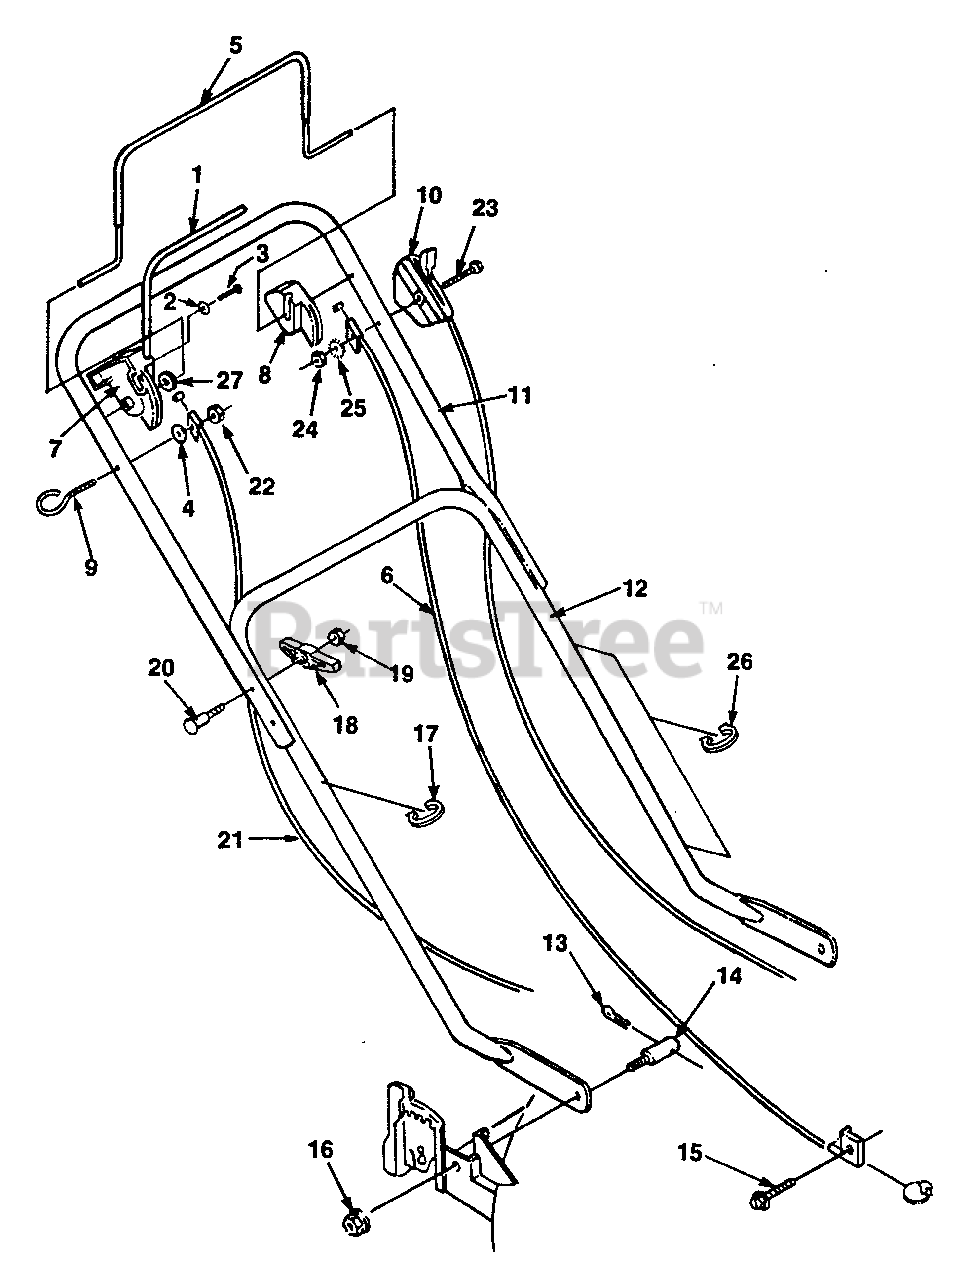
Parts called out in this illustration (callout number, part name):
1	TRACTION LEVER
2	WASHER - 1/4"
3	SCREW - 10-16×1/2" -- HEX CAP
4	WASHER - CARVED
5	BAIL - BRAKE CONTROL
6	CONTROL, MANUAL START
7	ACTUATOR - RIGHT
8	ACTUATOR - LEFT
9	EYEBOLT - (1/4-20×1 3/4")
10	CONTROL, THROTTLE
11	HANDLE - UPPER
12	HANDLE - LOWER
13	PIN, COTTER
14	STUD
15	SCREW - 10-24×1/2"
16	NUT - 5/16-18 -- FLANGE
17	CLAMP - CABLE SINGLE
18	KNOB - HANDLE
19	NUT - 5/16-18
20	BOLT
21	CABLE - TRACTION CONTROL
22	LOCKNUT - 1/4-20
23	BOLT
24	NUT - 5/16-18
25	LOCKWASHER - 1/4" -- EXTERNAL
26	CLAMP - DOUBLE
27	WASHER - 5/16"
